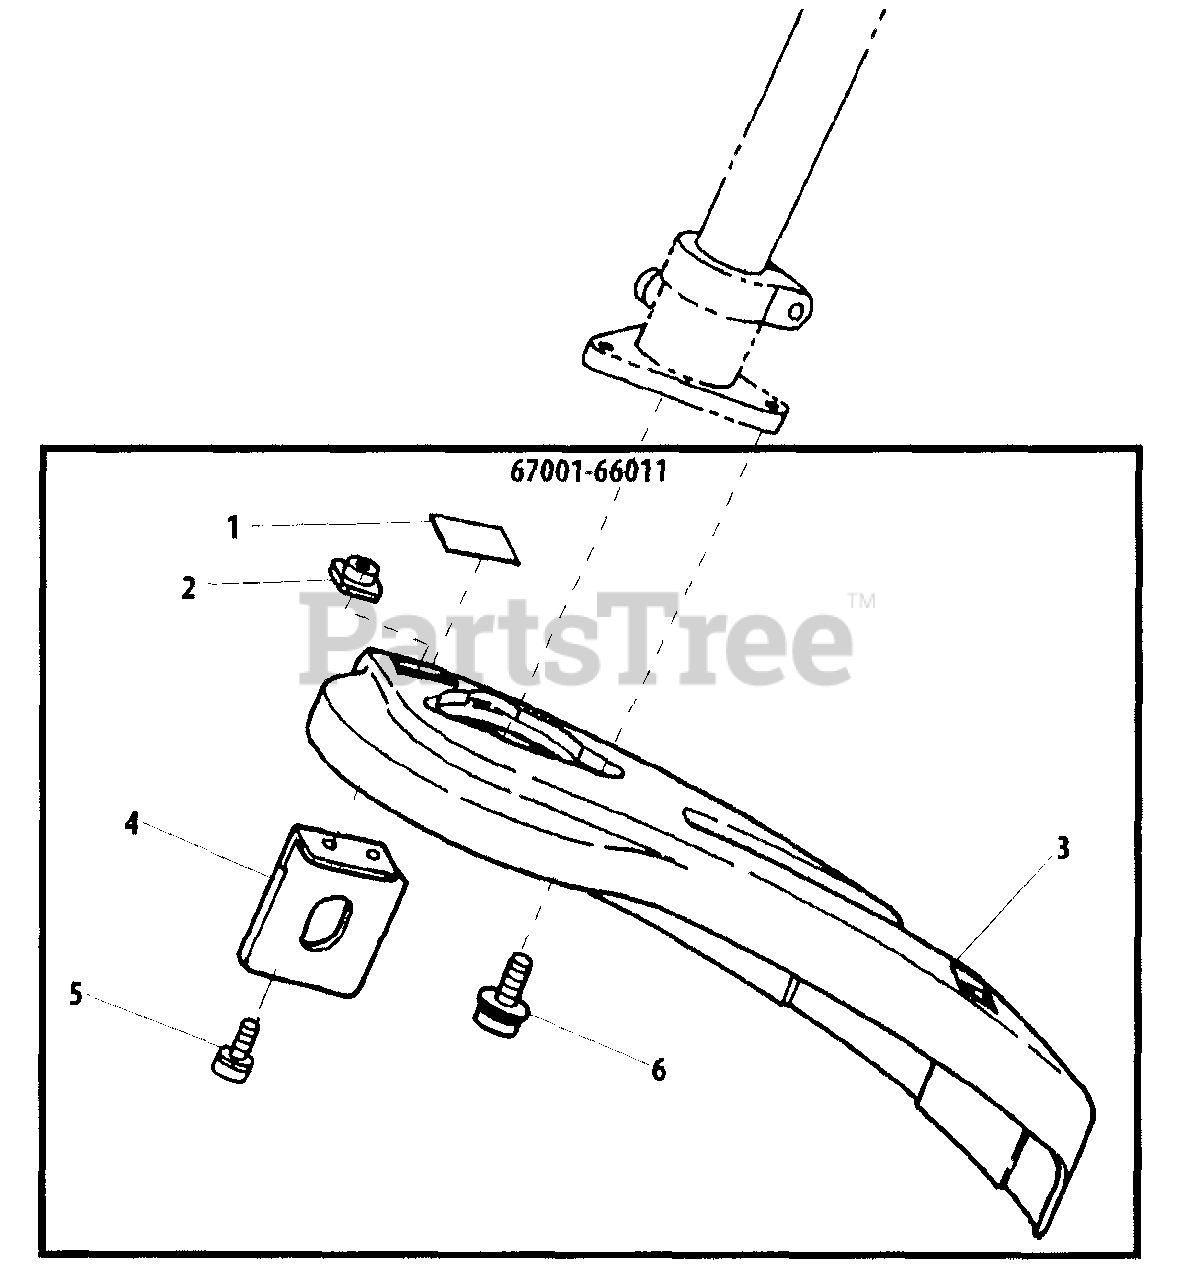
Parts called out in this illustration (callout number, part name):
1	LABEL, CAUTION
2	NUT - NYLON
3	GUARD
4	CUTTER
5	SCREW
6	SCREW M5×16
67001-66011	DEBRIS SHIELD KIT
